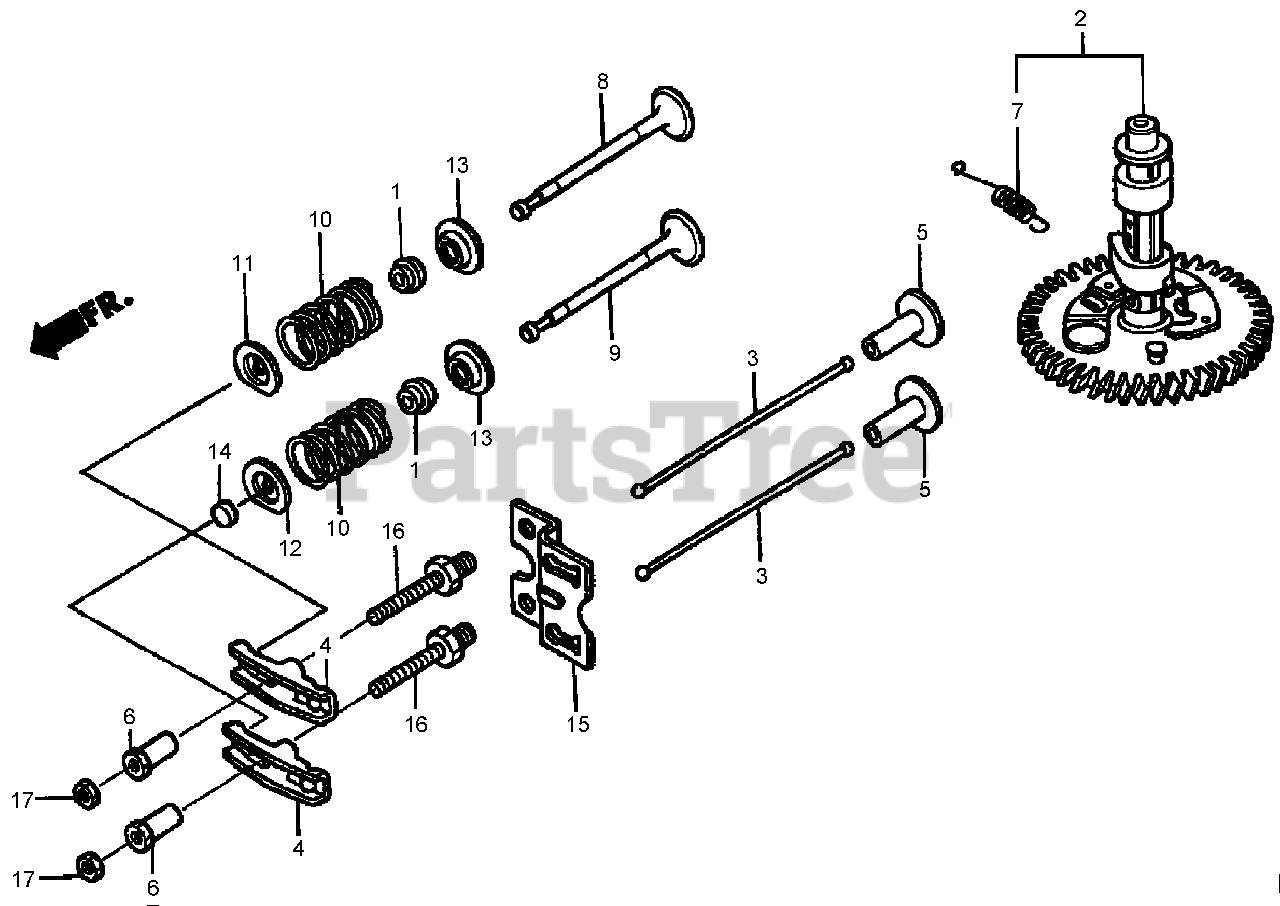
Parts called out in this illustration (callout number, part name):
1	SEAL-STEM, VALVE
2	CAMSHAFT ASM
3	ROD-PUSH
4	ARM-ROCKER, VALVE
5	LIFTER-VALVE
6	PIVOT-ARM, ROCKER
7	SPRING-RETURN, WEIGHT
8	VALVE-INTAKE
9	VALVE-EXHAUST
10	SPRING-VALVE
11	RETAINER-VALVE, INTAKE
12	RETAINER-VALVE, EXHAUST
13	SEAT-SPRING, VALVE
14	ROTATOR-VALVE
15	GUIDE-ROD, PUSH
16	BOLT-PIVOT (8 mm)
17	NUT-ADJUSTING, PIVOT
